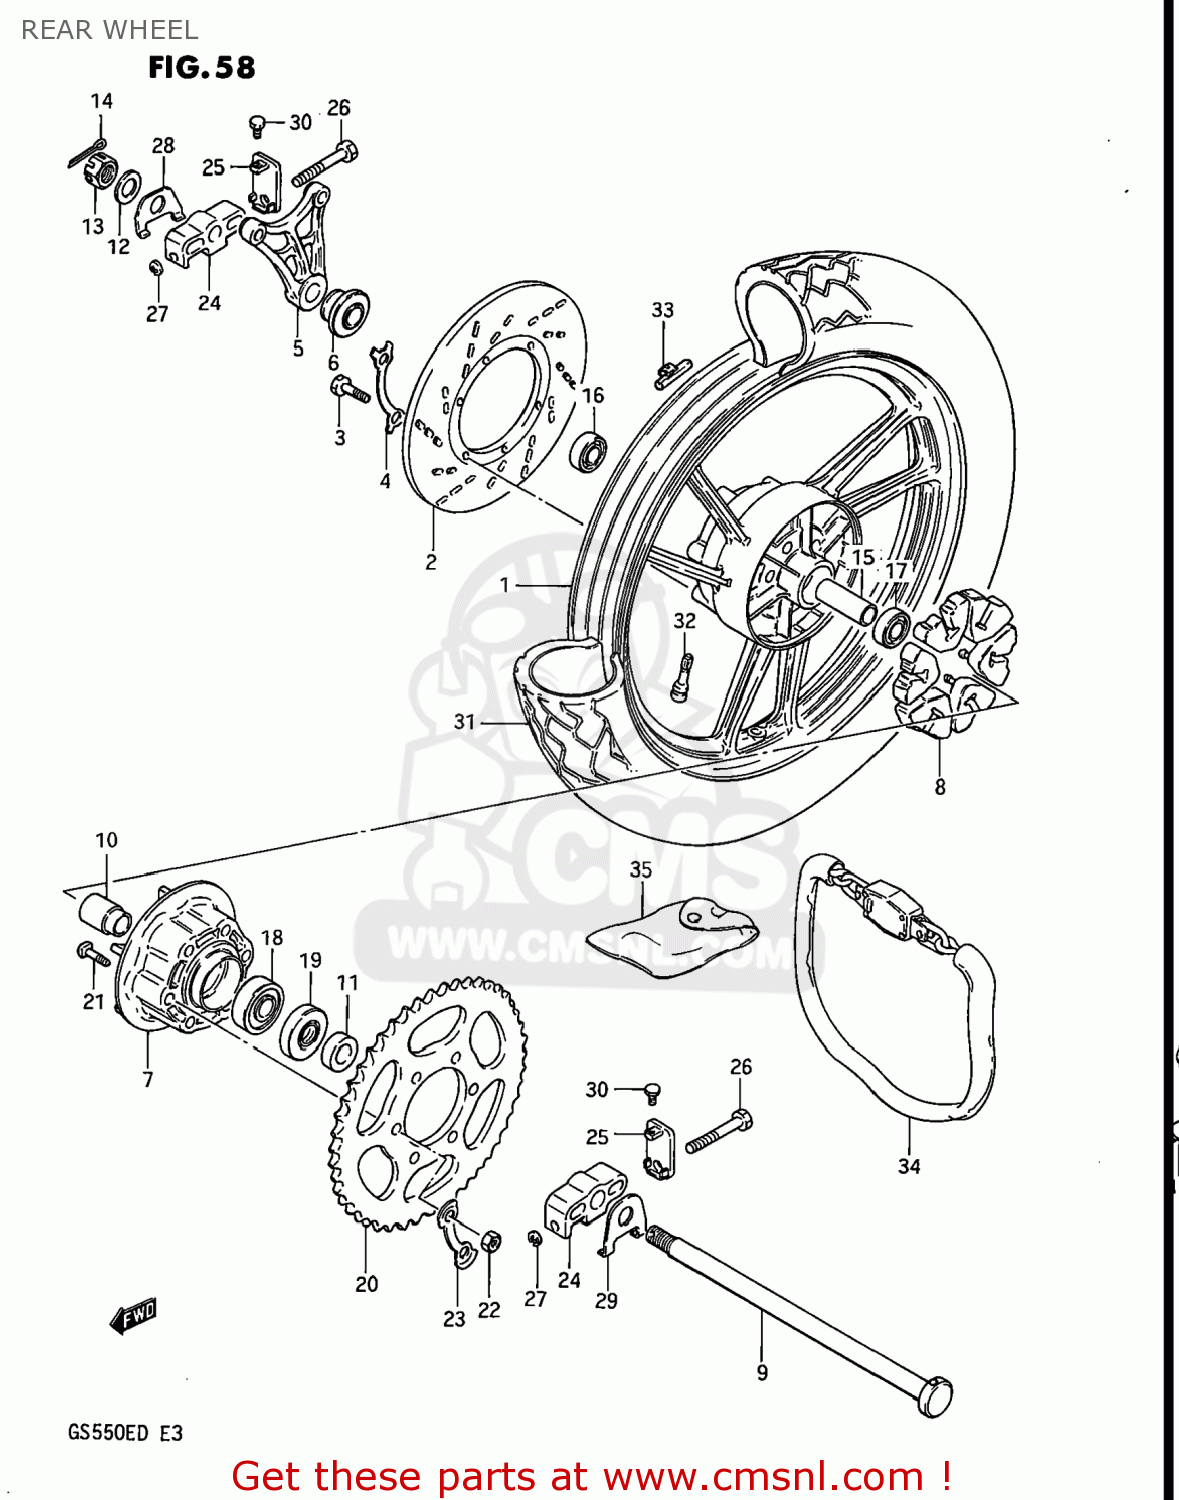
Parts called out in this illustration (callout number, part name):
1	WHEEL,REAR
2	DISK, REAR BRAKE
3	BOLT(8X25)
4	WASHER
5	BRACKET,RR,CALIPER
6	SPACER,REAR AXLE
7	DRUM,REAR SPROCKET MOUNT
8	ABSORBER,RR HUB SHOCK
9	AXLE,REAR
10	SPACER,REAR HUB BEARING
11	SPACER (17X30.5X13.5)
12	WASHER
13	NUT
14	PIN,COTTER
15	SPACER(17.5X25X81)
16	BEARING
17	BEARING
18	BEARING
19	SEAL,OIL(30.5X52X8)
20	SPROCKET,REAR
21	BOLT
22	NUT
23	WASHER
24	BODY,CHAIN ADJUSTER
25	PLATE,CHAIN ADJUSTER
26	BOLT,CHAIN ADJUSTER
27	E RING
28	WASHER,CHAIN ADJUSTER RH
29	WASHER,CHAIN ADJUSTER
30	BOLT(5X8)
31	TIRE
32	VALVE,TIRE
33	BALANCER,WHEEL
34	LOCK SET,CHAIN
35	BAG,CHAIN LOCK
